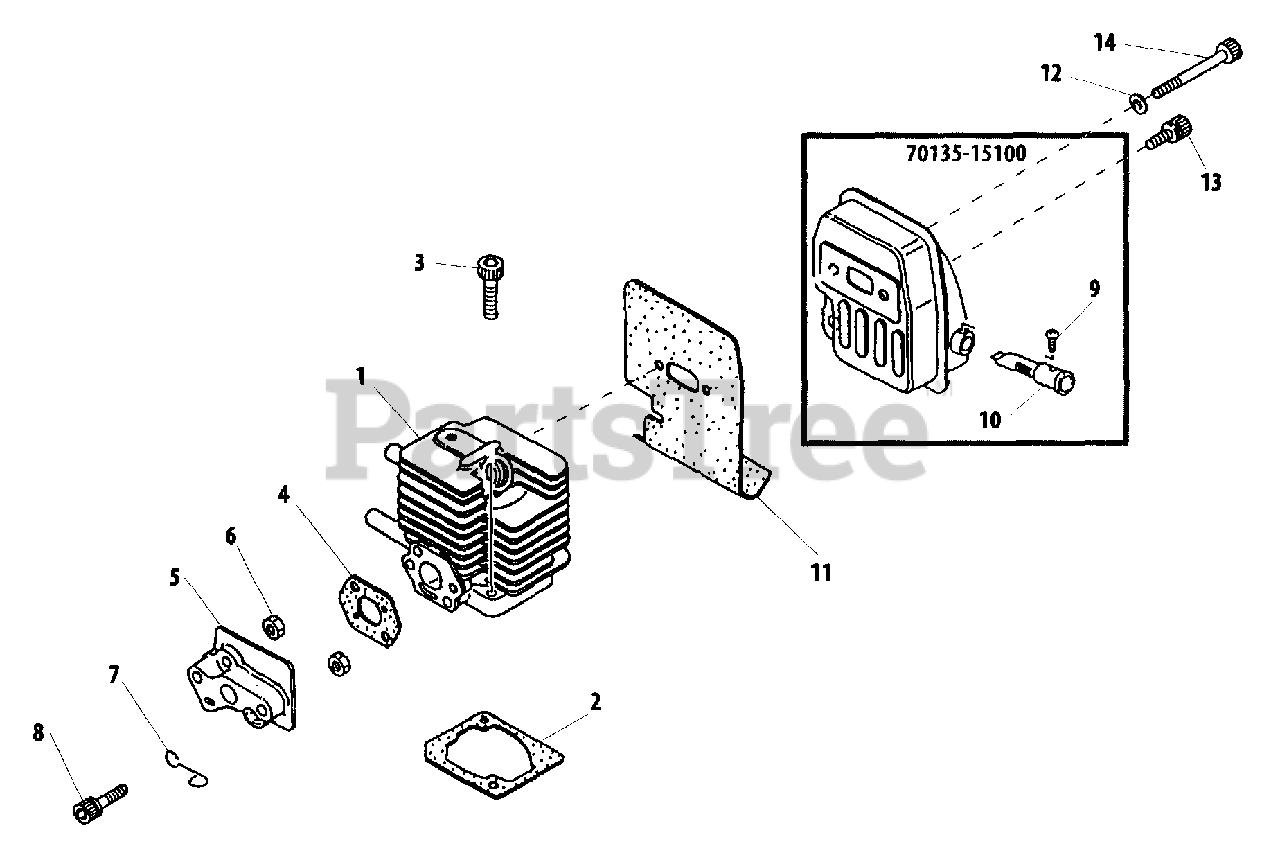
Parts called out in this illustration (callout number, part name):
1	CYLINDER
2	GASKET, CYLINDER
3	BOLT 5×25
4	GASKET, INTAKE
5	INSULATOR
6	NUT M5×6.3
7	CLIP, VENT ASSY
8	BOLT M5×25
9	SCREW, TAPPING 3×6
10	SCREEN, SPARK ARRESTER
11	GASKET, EXHAUST
12	WASHER, FLAT 5.5×10×0.8
13	BOLT 5×12
14	BOLT M5×50
70135-15100	MUFFLER ASSY
